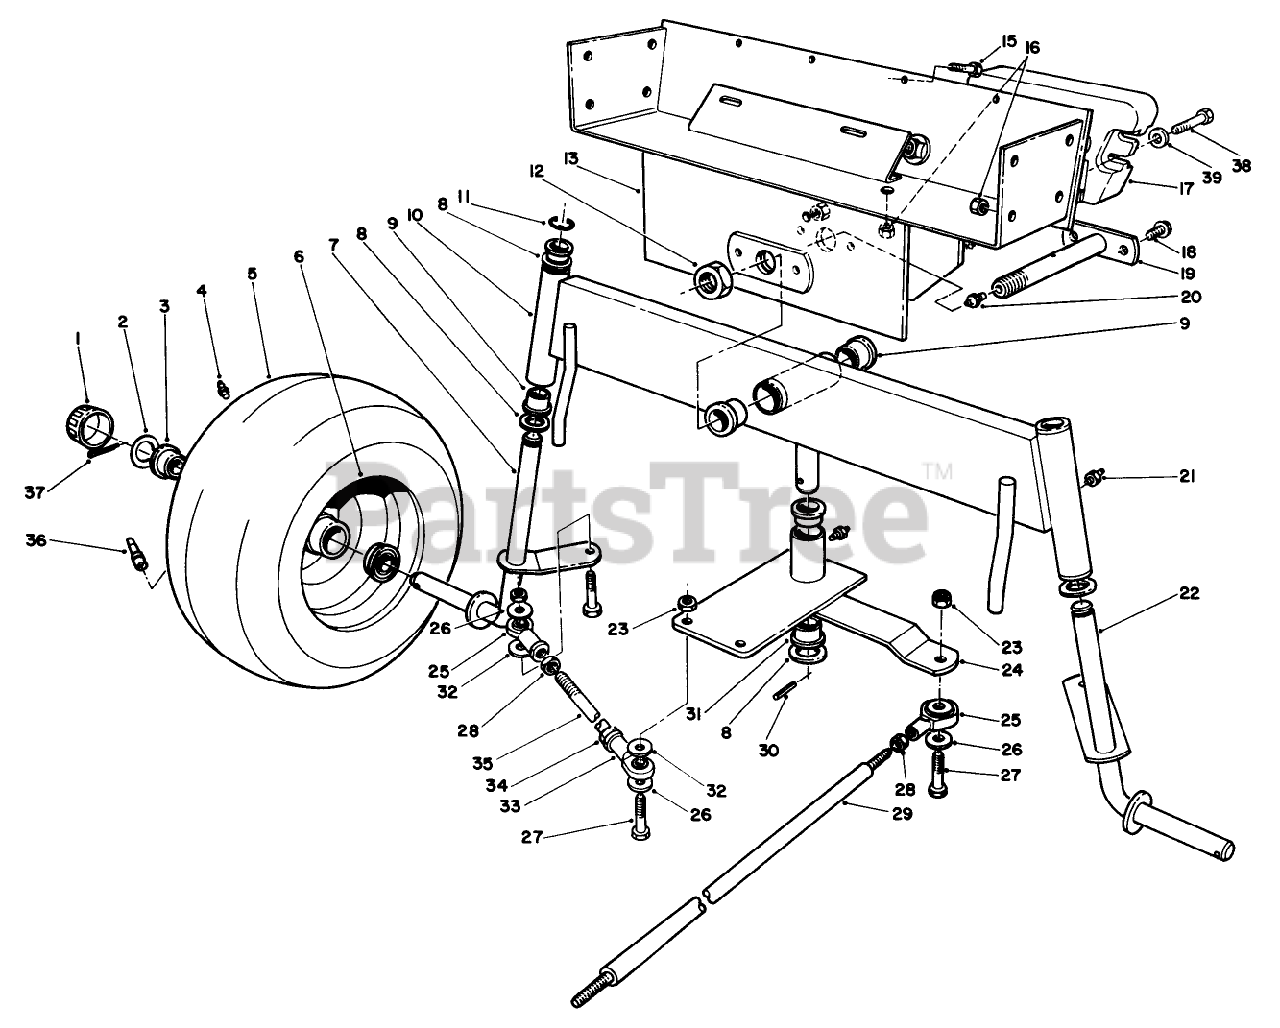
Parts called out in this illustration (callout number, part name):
1	CAP-HUB
2	WASHER-PLAIN
3	Bearing
4	FITTING-GREASE
6	FRONT WHEEL
7	Spindle R.H.
8	WASHER-THRUST
9	BUSHING PM
10	Axle-Rear (Incl. Ref. #9 & 20)
11	E-RING
12	NUT-LOCK NI
13	Frame-Rear
15	SCREW-HH
16	NUT-LOCK, NI
17	WEIGHT-REAR
18	SCREW-HHFTF
19	Axle-Pivot
20	FITTING-LUBE, 45 DEG
21	GREASE FITTING
22	Spindle LH.
23	NUT-HEX
24	Plate-Pivot (Incl. Ref. #20 & 30)
25	BALL JOINT RH
26	WASHER-FLAT
27	SCREW-HH
28	NUT-JAM
29	Rod-Steering
30	PIN-ROLL
31	BEARING-FLANGE
32	WASHER
33	BALL JOINT LH
35	TIE ROD - STEERING
36	STEM-VALVE
37	PIN-COTTER
38	SCREW-HH
39	WASHER-LOCK
